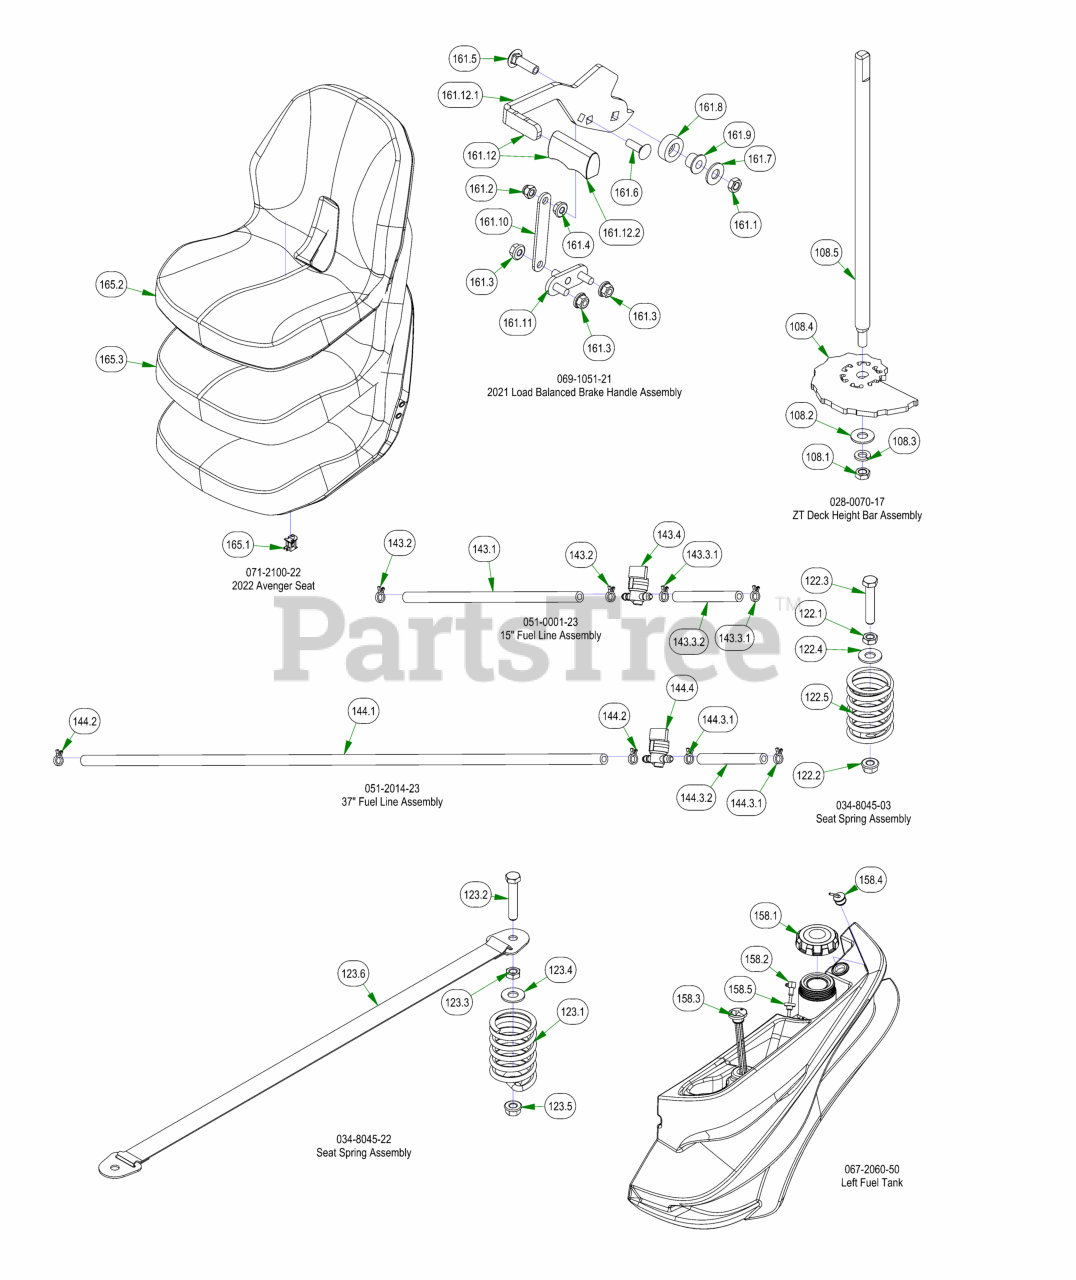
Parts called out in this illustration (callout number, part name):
108	ZT Deck Height Bar Assembly
108.1	3/8-24 HEX NUT ZINC YELLOW
108.2	3/8 FLAT WASHER USS (1" OD) ZINC
108.3	3/8 SPLIT LOCKWASHER ZINC
108.4	2017 MZ/ZT Cam Plate
108.5	2017 Deck Height Dial Rod ZT
122	Seat Spring Assembly
122.1	3/8-16 Half Jam Nut
122.2	3/8-16 HEX SERRATED FLANGE NUT HARD/ZINC
122.3	3/8-16 X 2 HEX CAP SCREW (GR.5) ZINC
122.4	3/8 FLAT WASHER USS (1" OD) ZINC
122.5	Seat Spring
123	Seat Spring Assembly
123.1	Seat Spring
123.2	3/8-16 X 2 HEX CAP SCREW (GR.5) ZINC
123.3	3/8-16 Half Jam Nut
123.4	3/8 FLAT WASHER USS (1" OD) ZINC
123.5	3/8-16 HEX SERRATED FLANGE NUT HARD/ZINC
123.6	Seat Strap with Buckles
143	15" Fuel Line Assembly
143.1	11" 1/4 Fuel Line
143.2	1/4 Fuel Hose Clamp
143.3	Fuel Line 4" Section with Clamps
143.3.1	1/4 Fuel Hose Clamp
143.3.2	4" 1/4 Fuel Line
143.4	2 Way Fuel Shut-Off Valve
144	37" Fuel Line Assembly
144.1	37" 1/4 Fuel Line
144.2	1/4 Fuel Hose Clamp
144.3	Fuel Line 4" Section with Clamps
144.3.1	1/4 Fuel Hose Clamp
144.3.2	4" 1/4 Fuel Line
144.4	2 Way Fuel Shut-Off Valve
158	Left Fuel Tank
158.3	Fuel Gauge w/Grommet
158.4	Rollover Valve W/Grommet
158.5	Pick-Up Grommet
161	2021 Load Balanced Brake Handle Assembly
161.1	3/8-16 HEX JAM 2-WAY REVERSIBLE CENTER LOCKNUT ZINC
161.2	5/16-18 NYLON INSERT CAP LOCKNUT ZINC (BLK CAP)
161.3	5/16-18 NYLON INSERT FLANGE LOCKNUT ZINC
161.4	5/16-18 HEX SERRATED FLANGE NUT HARD/ZINC
161.5	3/8-16 X 1-1/4 CARRIAGE BOLT ZINC
161.6	5/16-18 X 1 CARRIAGE BOLT (GR.8) ZINC
161.7	3/8 FLAT WASHER USS (1" OD) ZINC
161.8	2015 Brake Lever Spacer
161.9	.377 ID X .625 OD X .500 HGT X .880 FLNG DIA X .060 FLNG THK
161.10	Brake Cable Extension Plate
161.11	Brake Load Balancer Lower Weldment
161.12	Load Balanced Brake Handle with Grip
161.12.1	Switch Relocation Brake Handle
161.12.2	Brake Handle Rubber
165	2022 Avenger Seat
165.1	Seat Switch
165.2	Avenger Seat Cover
165.3	Water Proofing Protection
